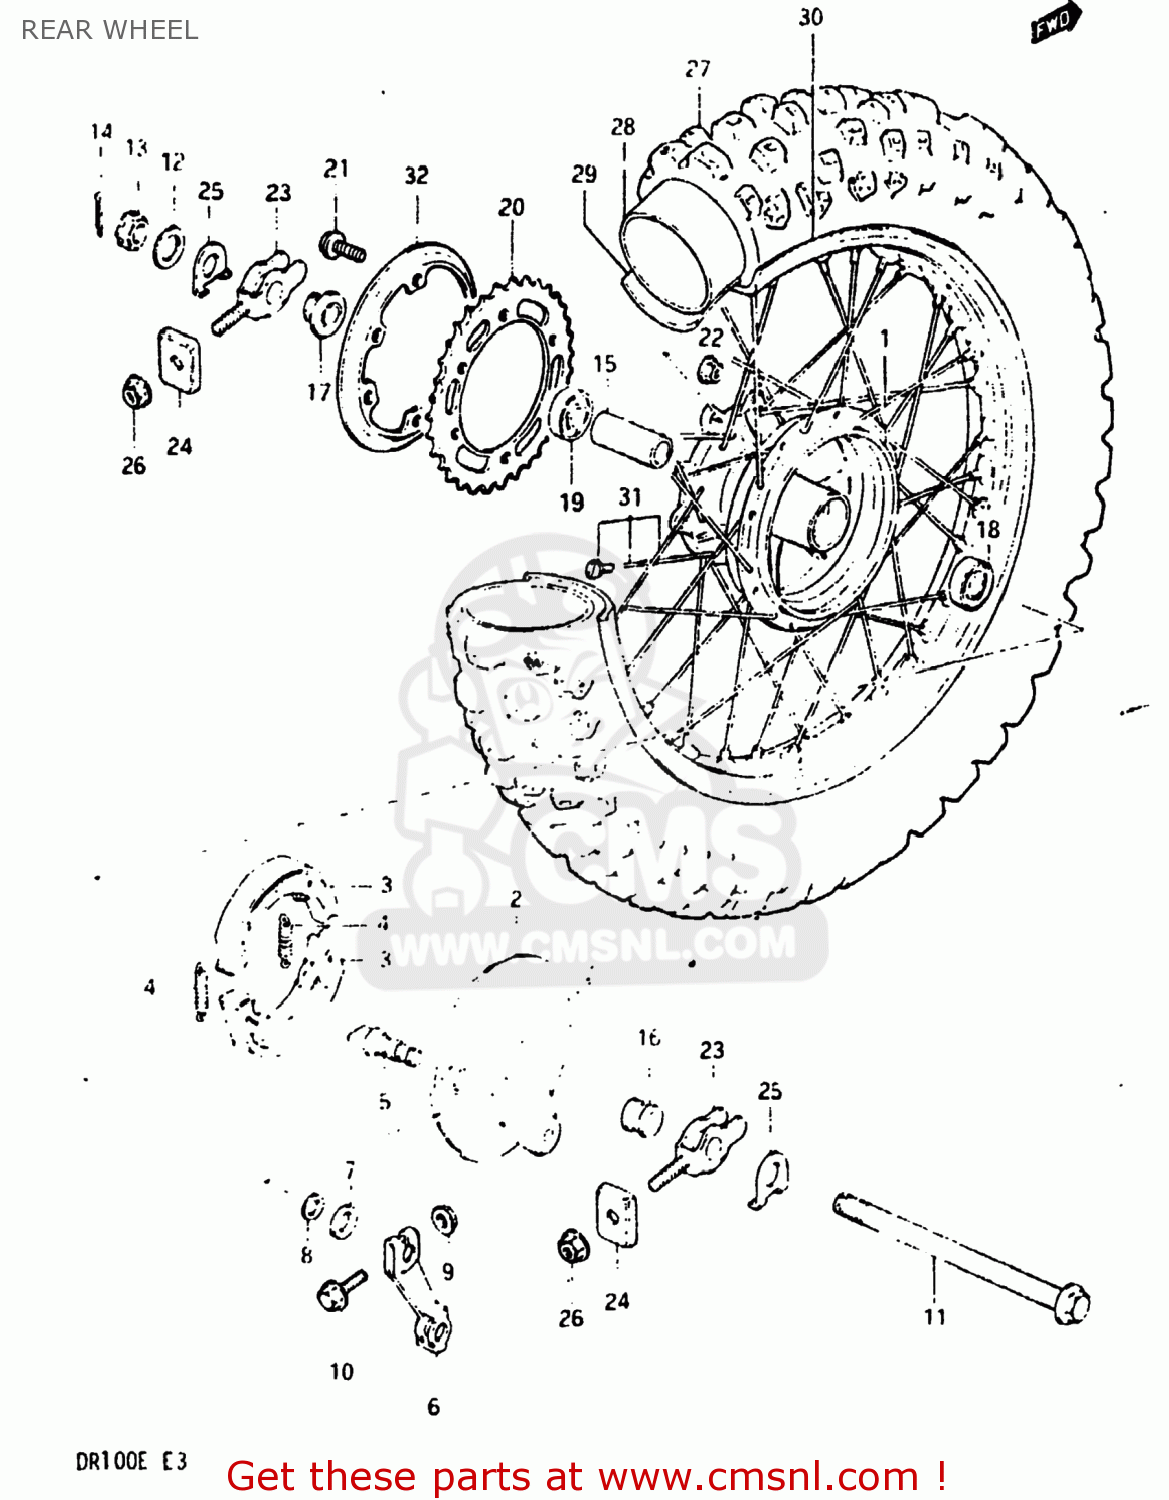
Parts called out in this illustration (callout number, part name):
1	HUB,RR WHEEL
2	PANEL,ANCHOR
3	SHOE,BRAKE
4	SPRING(L:34)
5	CAM,FRONT BRAKE
6	LEVER,RR BRAKE CAM
7	WASHER (14.5X22X1.6)
8	O-RING (D:2.4 ID:13.8)
9	NUT
10	BOLT 6X35
11	AXLE,REAR
12	WASHER
13	NUT
14	COTTER PIN
15	SPACER(15.3X21.7X97)
16	SPACER,REAR AXLE
17	SPACER,REAR AXLE
18	BEARING
19	BEARING
20	SPROCKET,RR(42T)
21	BOLT(8X33)
22	NUT
23	ADJUSTER,CHAIN
24	ADJUSTER,CHAIN
25	WASHER,CHAIN ADJUSTER
26	NUT
27	TIRE 4.10-14
28	TUBE ASSEMBLY,WHEEL,INNER
29	PROTECTOR,INNER TUBE
30	RIM,REAR WHEEL
31	SPOKE ASSY,RR WHEEL
32	PLATE,CHAIN SIDE
